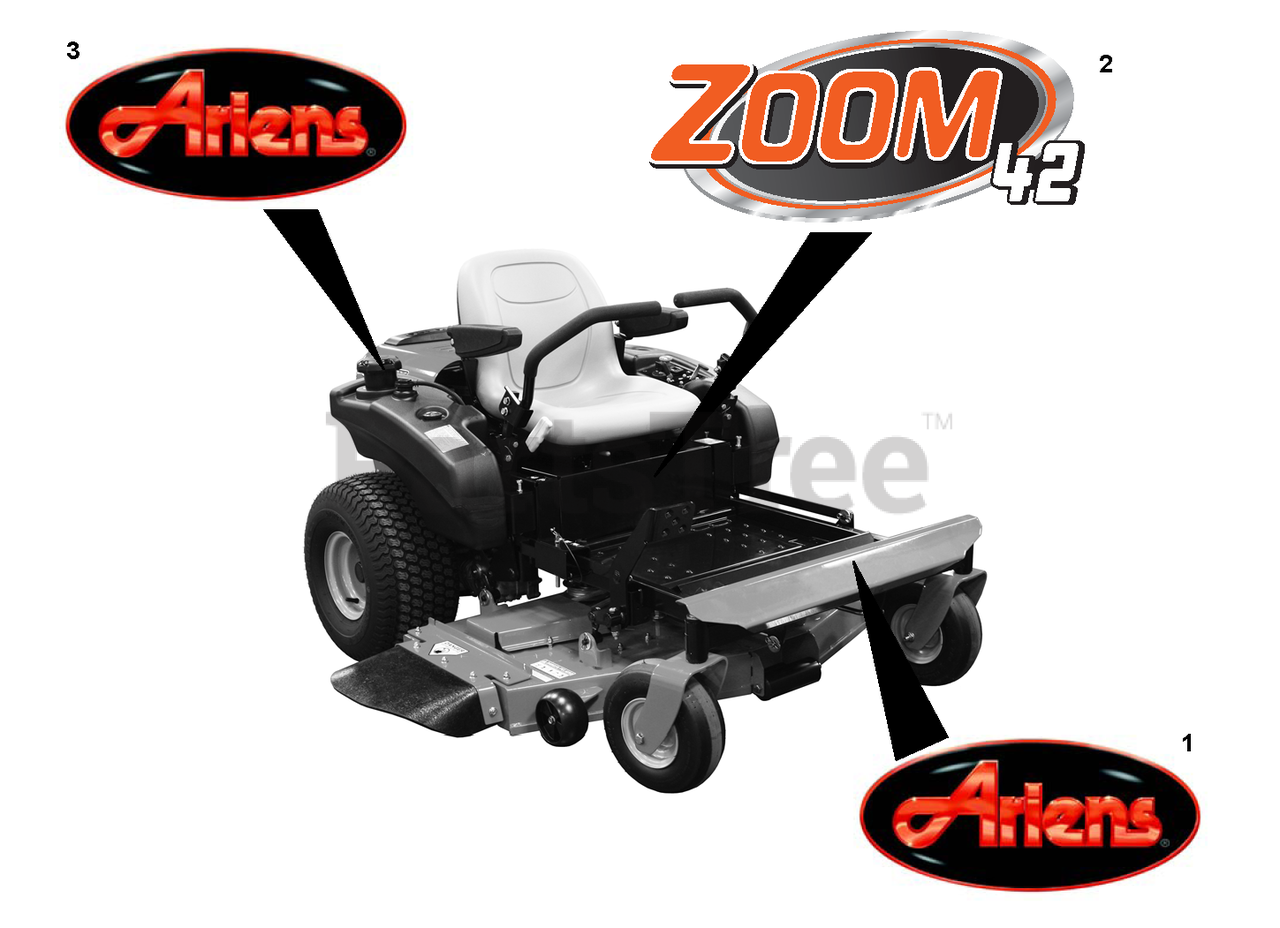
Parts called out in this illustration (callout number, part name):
1	DECAL, ARIENS JEWEL (LARGE)
2	DECAL, ZOOM42
3	DECAL, ARIENS JEWEL
